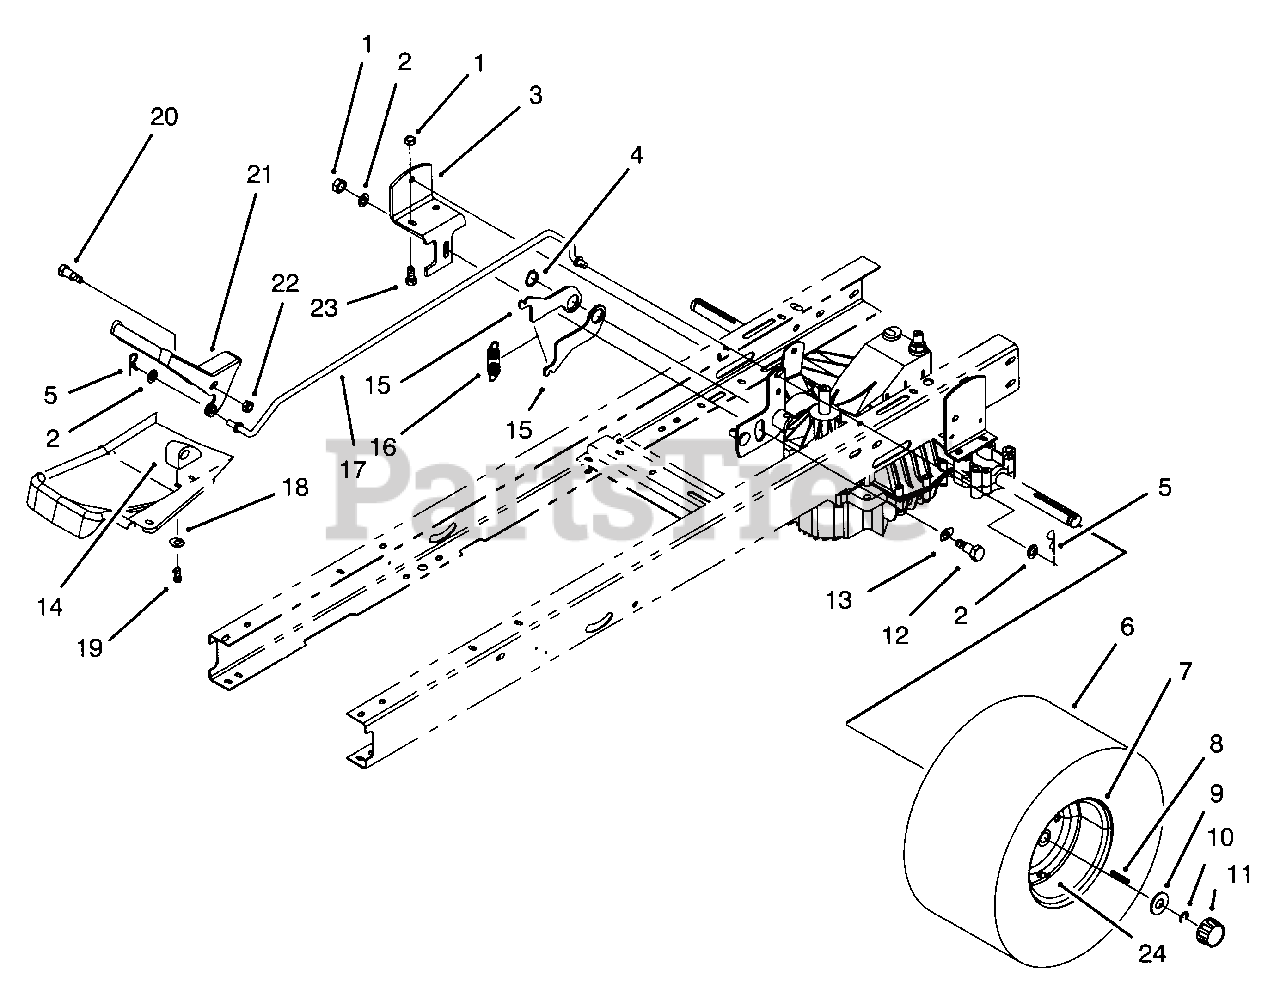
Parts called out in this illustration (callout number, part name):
1	Nut-Lock
2	Washer-Flat
3	Bracket-Neutral Adj.
4	Ring-External Retaining
5	Pin-Cotter
8	Key-Square
12	Bolt-Shoulder
13	Bearing-Thrust
14	Block-Pivot
15	Lever-Neutral Control
16	Spring-Extension
17	Rod-Speed Control
18	Washer-Flat
19	Screw-Plastite
20	Bolt-Shoulder
21	Pedal-Speed Control
22	Nut-Lock
23	Screw-Hex Hd. Cap
24	Valve Stem w/Cap
